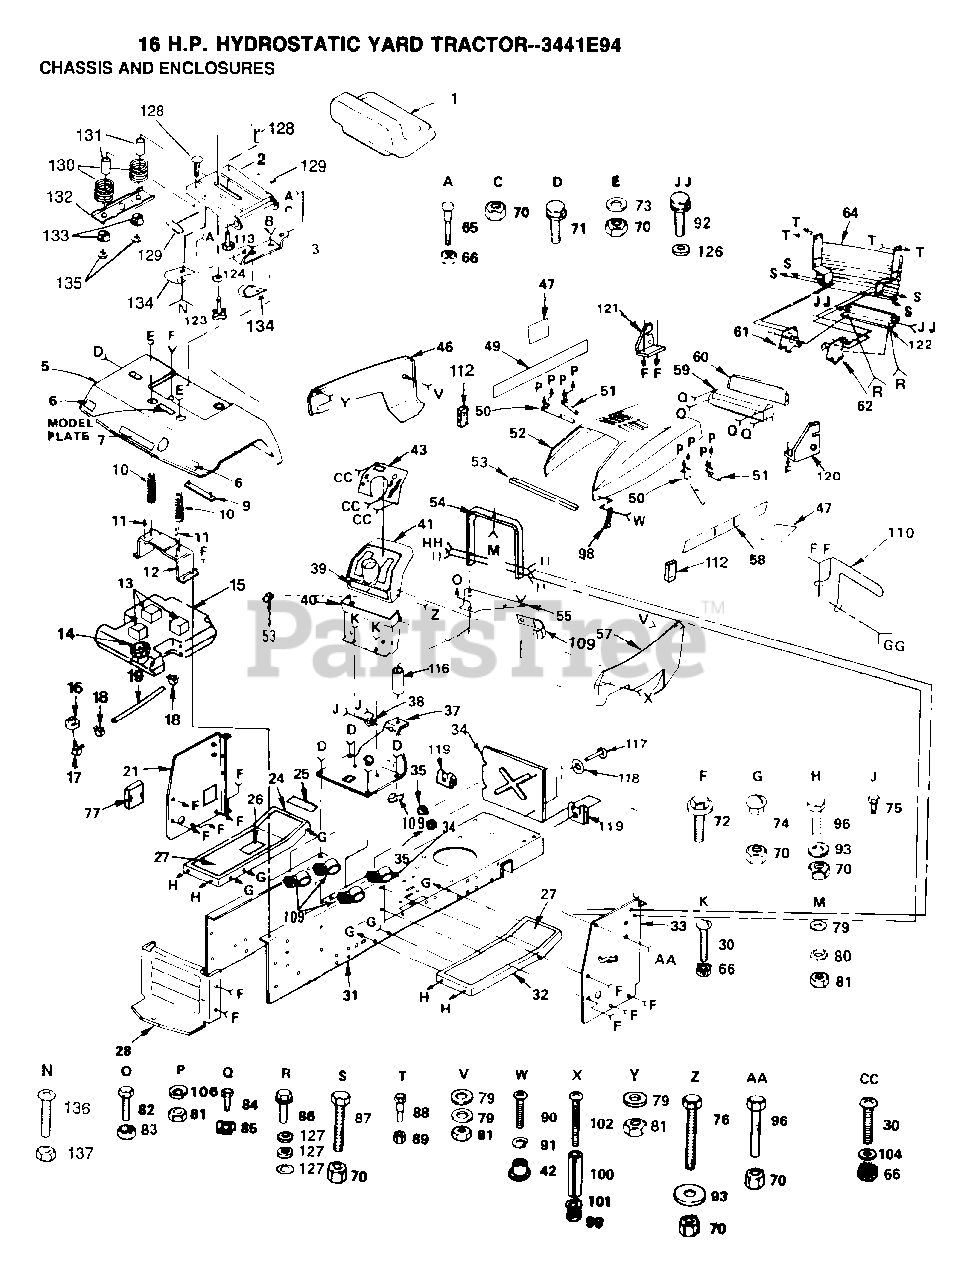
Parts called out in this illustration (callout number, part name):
6	REFLECTOR-TAIL YT
11	NUT-PUSH YT
13	PAD-SPACER T
16	BUSHING OUTLET T
17	FUEL TANK STEM GT
20	SPACER WASHER YTH
21	DASH PANEL T
25	DECAL T
26	DECAL DRIVE BELT
27	PAD FOOTREST T
29	DEFLECTOR HYT
30	SCREW
37	SADDLE
40	LOWER DASH
42	WELDNUT
44	WASHER
49	DECAL - HOOD, L.H.
53	FOAM STRIP T
58	DECAL- HOOD, R.H.
60	LENS LT
61	SUPPORT LH YTH
62	SUPPORT RH YTH
69	WASHER T
71	SCREW LT
72	SCREW
73	WASHER
74	BOLT
76	BOLT
77	COVER ACCESS
79	WASHER PM
82	BOLT
85	"""J"" FASTENER LT"
86	SCREW
87	BOLT
88	BOLT T
90	SCREW
91	LOCKWASHER
92	SCREW
93	WASHER
98	HOOD LATCH T
100	SPACER LT
101	WASHER
102	SCREW
104	WASHER
108	SCREW GTV
109	CLIP T
110	GUARD MUFFLER HYT
111	WASHER HYT
112	STRIP - FOAM
116	SPACER
118	RETAINER LT
119	RECEPTACLE LT
120	SUPPORT RH YTH
121	SUPPORT LH YTH
123	"KNOB 1/2"" YT"
124	WASHER
125	LOCKWASHER
126	LOCKWASHER GT
127	WASHER M
128	BOLT
129	STRIP FORM
130	SPRING
131	SPACER SPLIT
132	BRKT SWITCH
133	BUSHING
135	NUT T
137	"NUT,KEPS"
